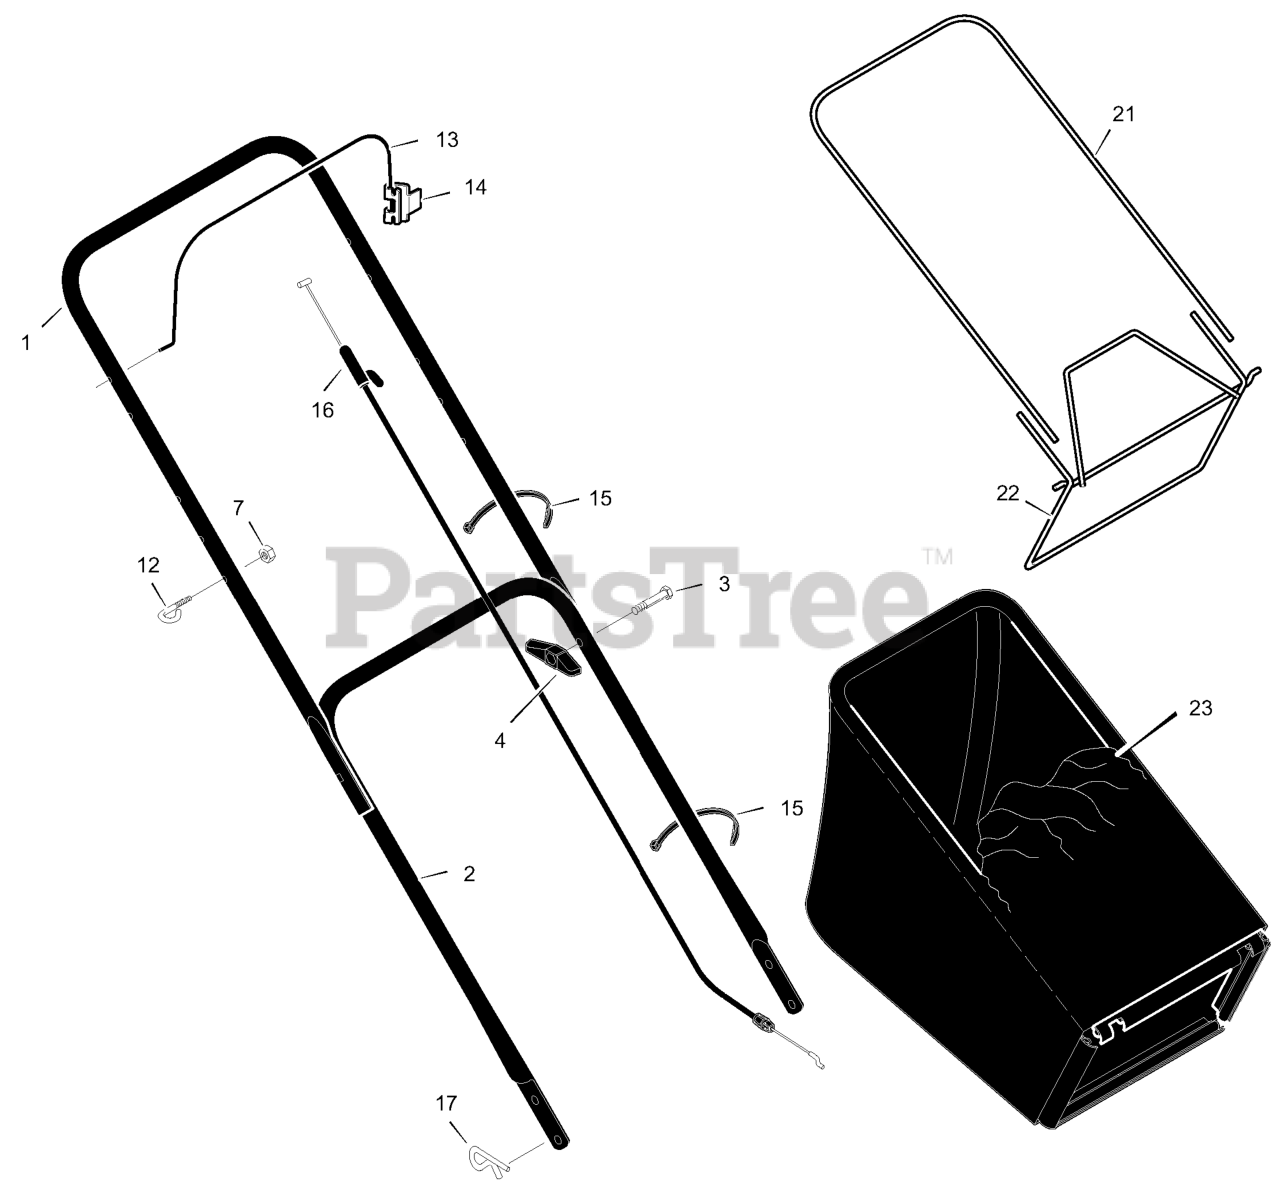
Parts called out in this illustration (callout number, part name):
1	Handle, Upper
2	Handle, Lower
4	Knob, Plastic
7	Locknut
12	Guide, Rope
13	Engine Stop Lever
14	Bracket, Stop Lever
15	Fastener, Cable
16	Engine Stop Cable
17	Hair Pin
21	Frame, Top
22	Frame Assembly
23	Bag, Cloth
